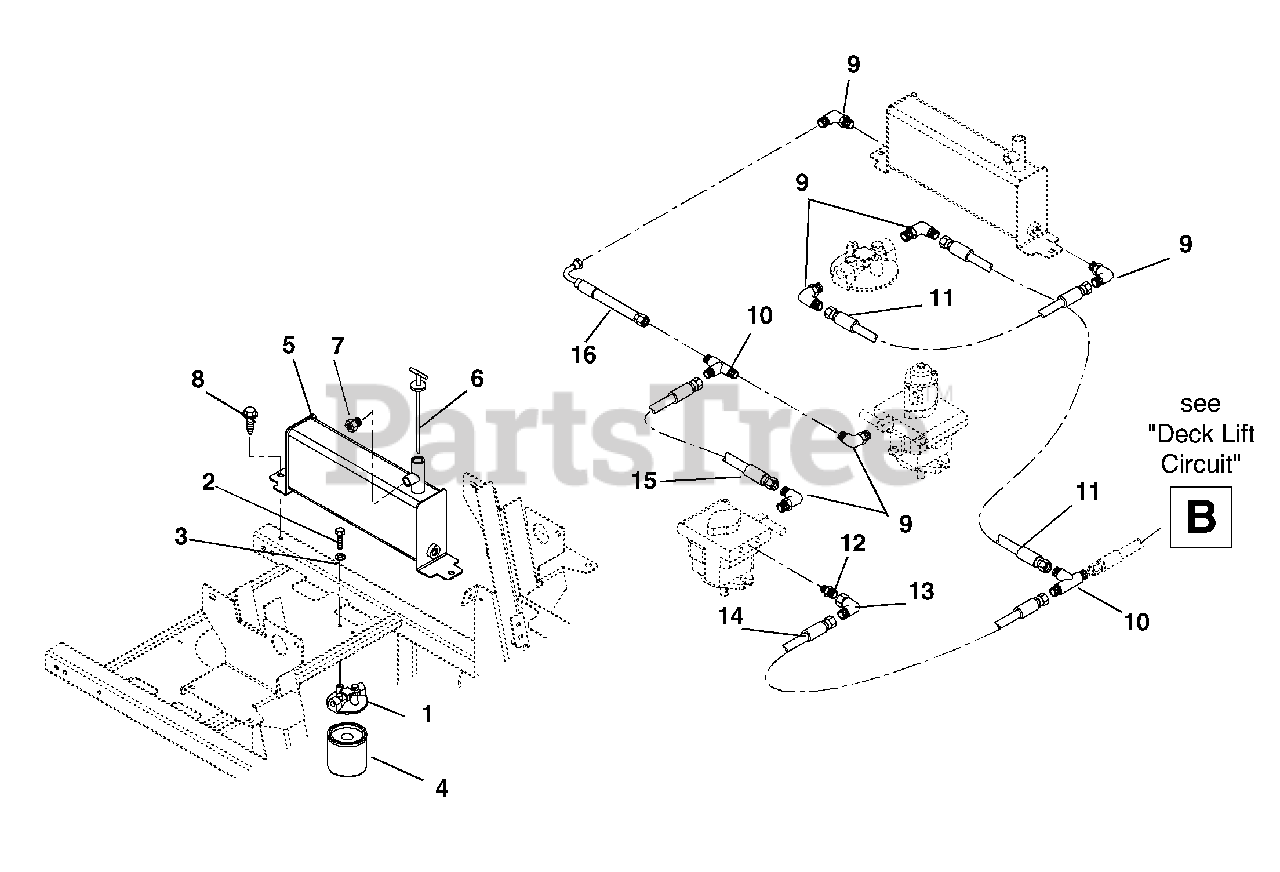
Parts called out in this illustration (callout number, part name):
1	Head-Filter
2	Bolt-Hex .25-20 x .50 Grade 5
3	Washer-Locking .25 x .062
4	Oil Filter
5	Tank-Hydraulic Weldment
6	Hydraulic Tank Dipstick
7	Plug-Breather .38
8	Screw-Tapping .38-16 x .75 Hex Washer Head
9	Adapter
10	Adapter-Tee .56-18
11	Hose-Hydraulic Valve to Tank
13	Adapter
14	Hose-Pump to Tee
15	Hose, Hydraulic
16	Hose, Hydraulic
